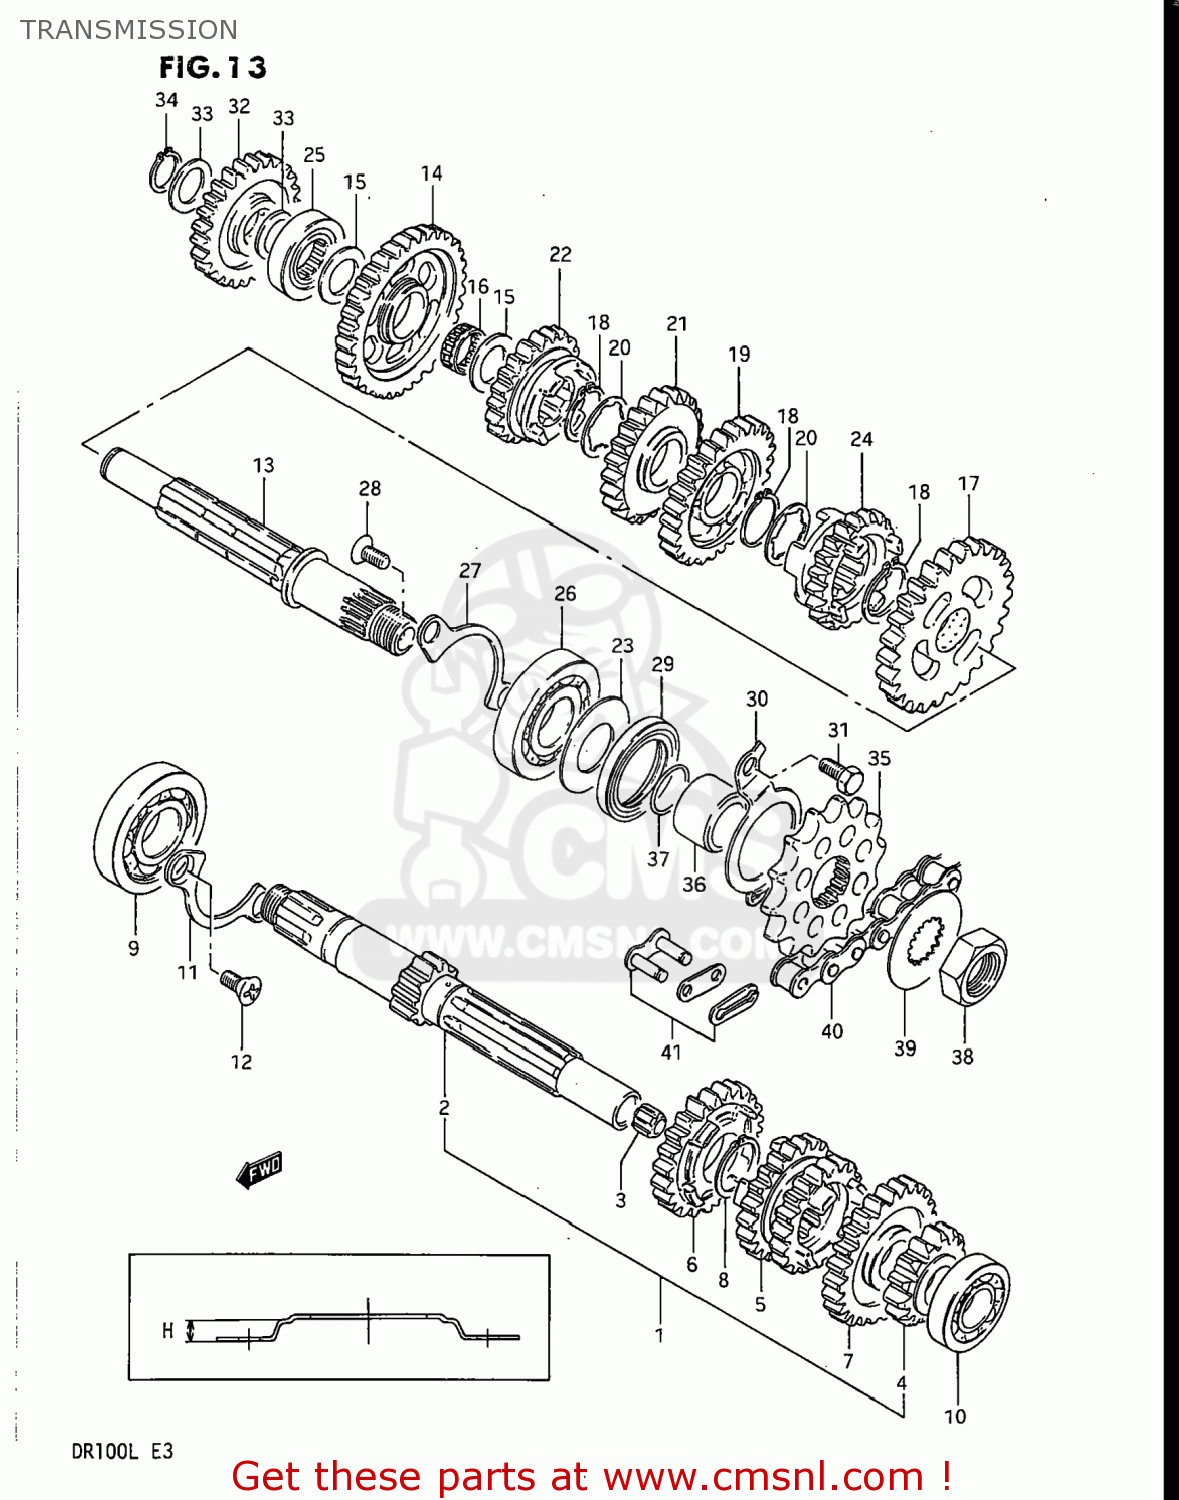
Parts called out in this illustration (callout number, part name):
1	SHAFT,COUNTER
2	SHAFT,COUNTER
3	BUSH
4	GEAR,SECOND DRIVE
5	GEAR,THIRD & FOURTH DRIVE,N
6	GEAR,FIFTH DRIVE
7	GEAR,SIXTH DRIVE
8	CIRCLIP
9	BEARING
10	BEARING
11	RETAINER,DRIVE SHAFT BEARING
12	SCREW
13	SHAFT,DRIVE
14	GEAR,FIRST DRIVEN
15	WASHER
16	BEARING(15X19X7.8)
17	GEAR,SECOND DRIVEN
18	CIRCLIP
19	GEAR,THIRD DRIVEN
20	WASHER,LOCK
21	GEAR,FOURTH DRIVEN
22	GEAR,FIFTH DRIVEN
23	WASHER,OIL SEALING
24	GEAR,SIXTH DRIVEN
25	BEARING(15X33X12)
26	BEARING
27	RETAINER,DRIVE SHAFT BEARING
28	SCREW
29	SEAL,OIL(27X40X6)
30	PLATE,DRIVESHAFT OIL
31	BOLT
32	GEAR,KICK STARTER IDLE(NT:26)
33	WASHER
34	CIRCLIP,15MM
35	SPROCKET,ENGINE(NT:13)
36	SPACER
37	O RING(D:2.4,ID:19)
38	NUT
39	WASHER,LOCK
40	CHAIN ASSEMBLY,DRIVE
41	JOINT,CHAIN
